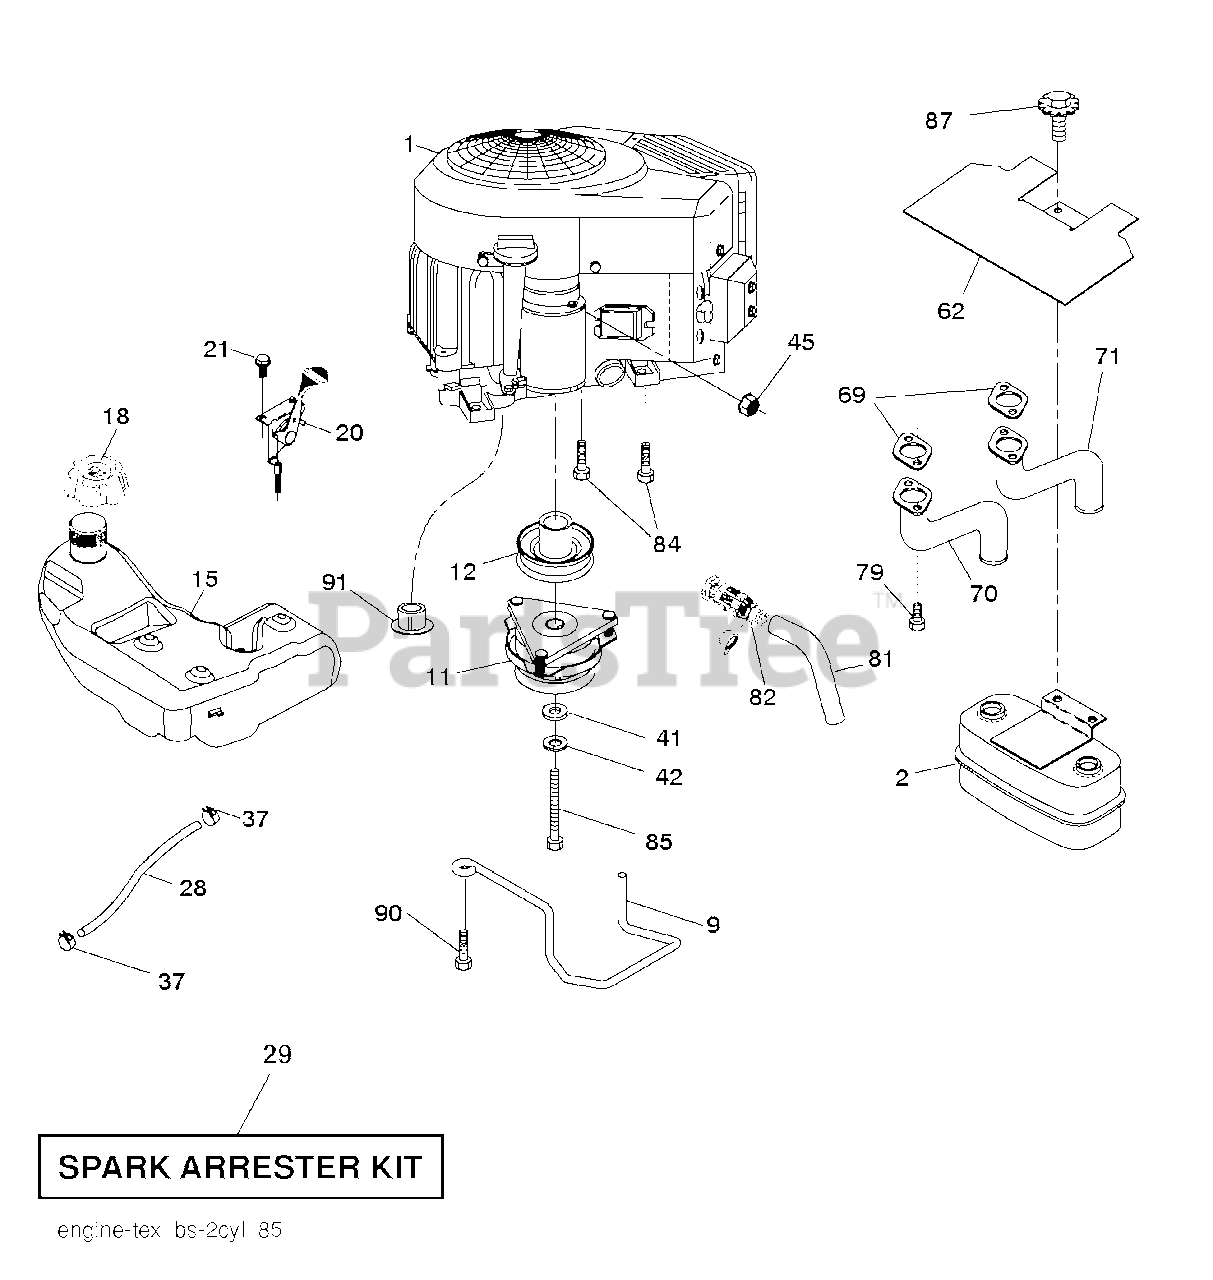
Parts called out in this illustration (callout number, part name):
2	MUFFLER.ASM.TWN.EXTNDED.DFLCTR
9	KEEPER.BELT.ENGINE.4.2
11	CLUTCH MZ ZTR GT.48/54"1.125"
12	PULLEY ENGINE
15	TANK.FUEL.4GAL
18	CAP.FL.R.3'N/CARB.H.CROWN.498
20	CONTROL.TH/CK.COBRA.B&S.TWN.
21	SCREW.#10 X 0.750.BOS
28	REPL BY 532 00 85-43
29	KIT.SPARK ARRESTOR 794945 B&S
37	HOSE CLAMP
42	LOCKWASHER
45	NUT
62	SHIELD.HEAT.MUFFLER
69	GASKET.MUFFLER
70	RP.EXHAUST.TUBE.LH.BS/TWIN
71	EXHAUST.TUBE.RH.BS/TWIN
79	SCREW.SOCKET.HEAD.5/16-18
81	TUBE, DRAIN OIL ASM.
82	VALUE.OIL.DRAIN
84	SCREW.3/8-16
85	BOLT HEX 7/16-20 X 3.75 GR. 5
87	BOLT, 5/16-18 X 1 3/4
90	SCREW 3/8-16X1
91	BUSHING.1.375OD
